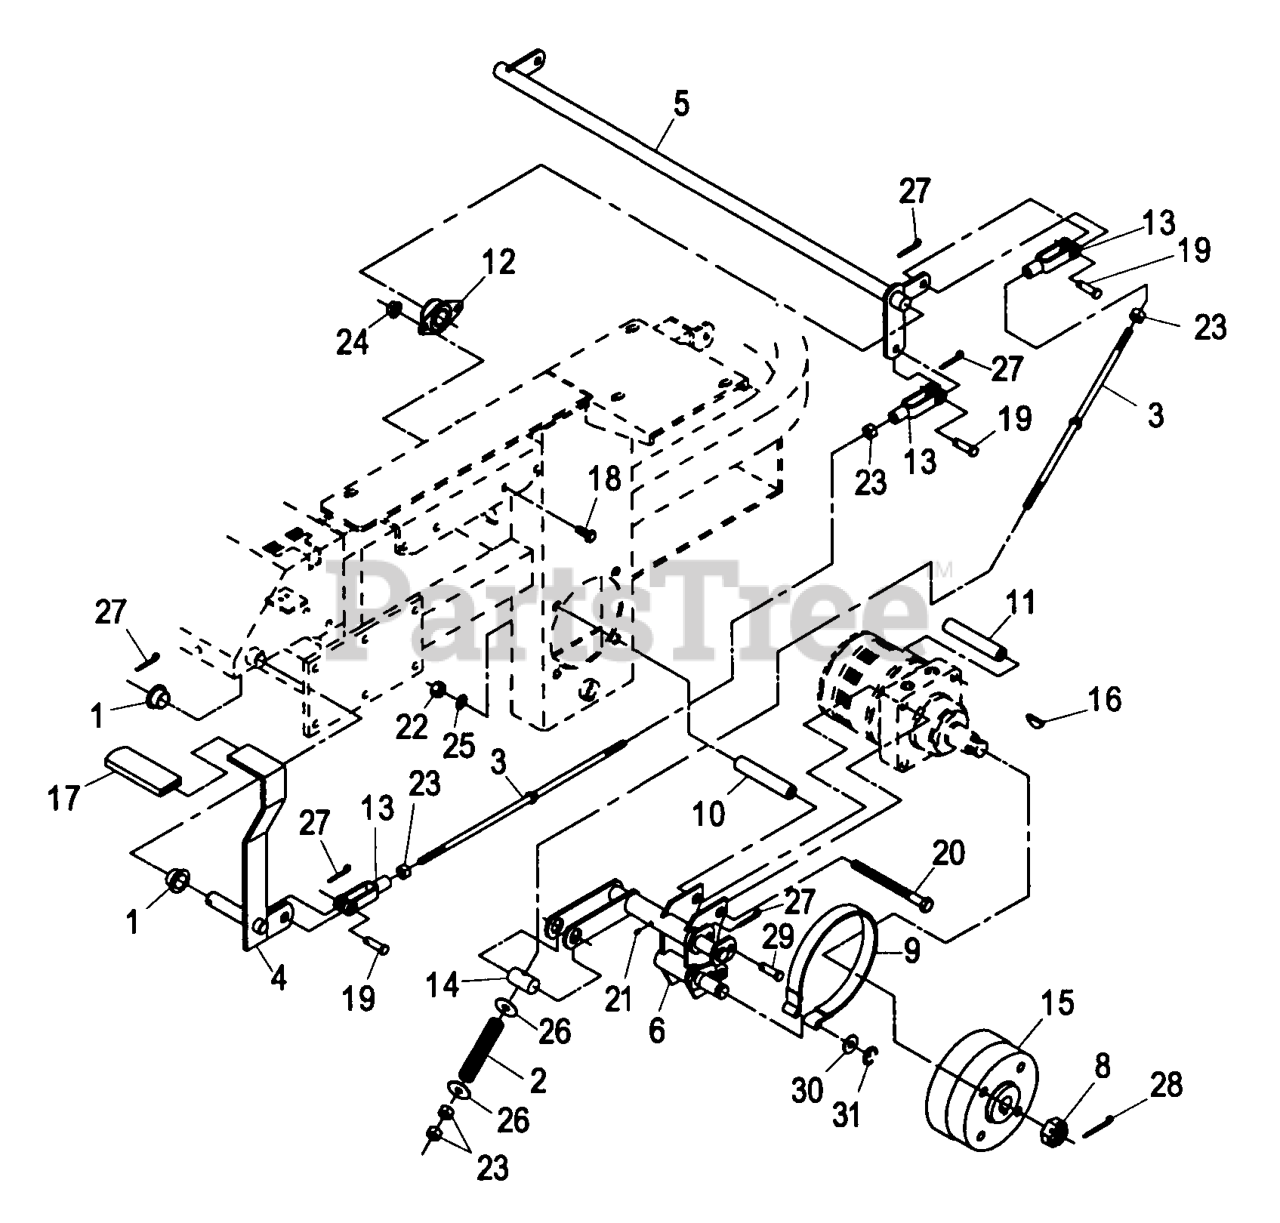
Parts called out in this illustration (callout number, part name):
1	BEARING-CONTROL
2	SPRING-BRAKE
3	ROD-BRAKE
4	BRAKE LEVER ASM
5	SHAFT-BRAKE
9	BAND,BRAKE
10	SPACER-WHEEL, SHORT
12	BEARING-FLANGE, SIDE
13	YOKE-LINKAGE, BRAKE
14	PIN-TRUNION
17	GRIP-LEVER
19	PIN-CLEVIS
28	PIN-COTTER
29	PIN,CLEVIS 3/8X2
